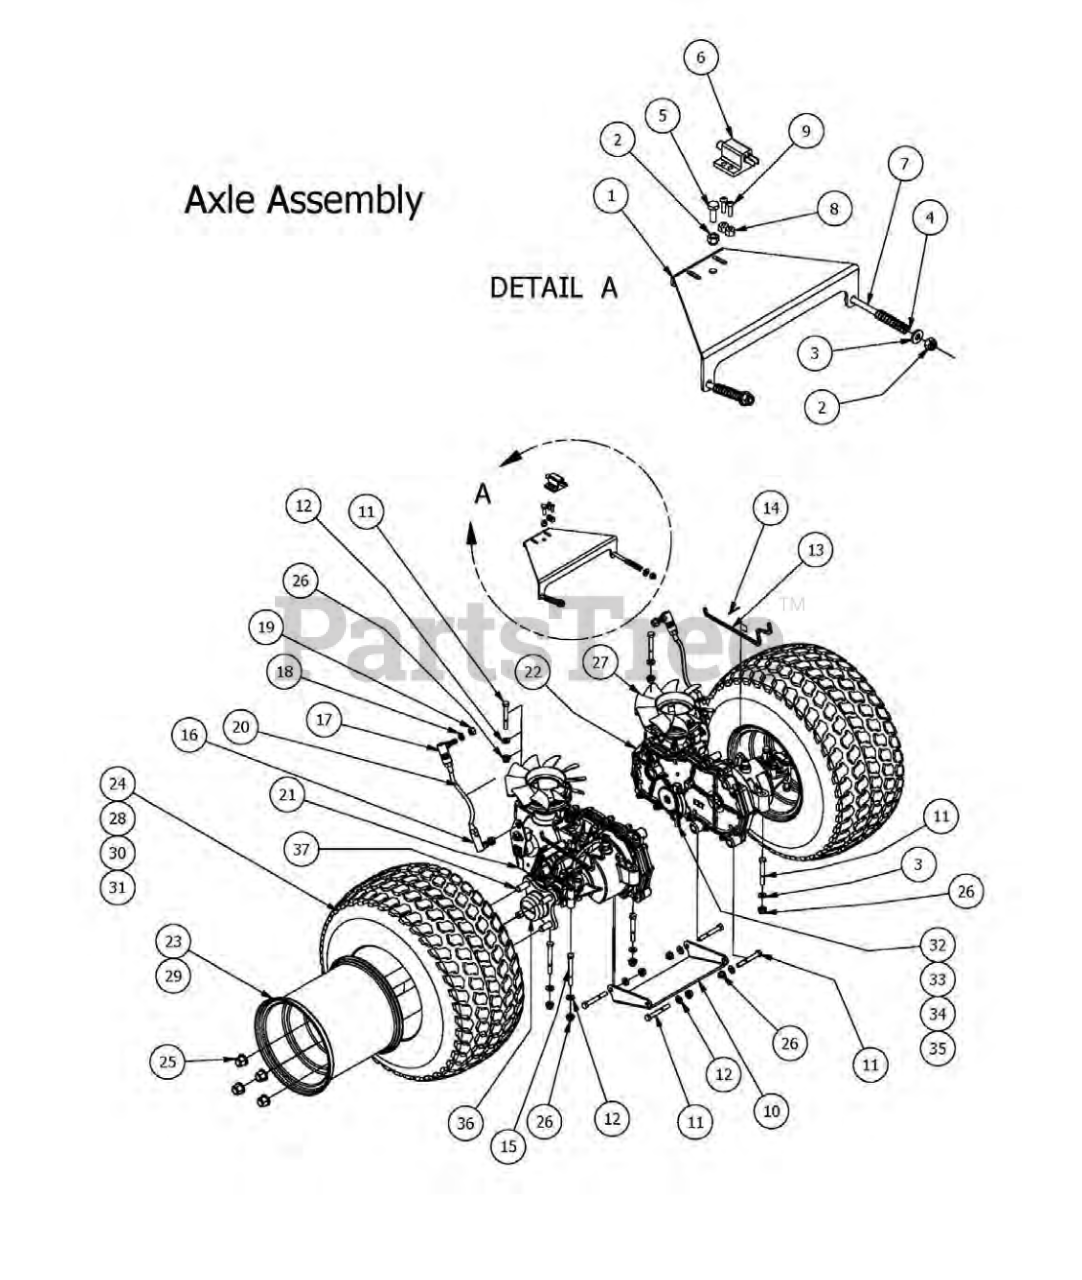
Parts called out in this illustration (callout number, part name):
1	MZ Brake Lock Bracket
2	1/4" Nylock Nut
3	1/4" Flat Washer
4	Brake Spring
5	1/4" x 3/4" Hex Bolt
6	Safety Switch
7	1/4-20 x2-1/2 Gr2 hex C/s zinc
8	10-24 Nylon Insert Locknut
9	10-24 X 5/8 BS Button Head Bolt
10	MZ Transaxle Support (Lower)
11	5/16" x 2 1/2" Bolt
12	5/16" Flat Washer
13	MZ Brake Release Bar
14	Cotter Pin-Brake bar on Mz
15	5/16" x 3" Hex Bolt
16	3/8-24 Ball Joint
17	Quick Release Ball Joint
18	3/8" Lock Washer
19	3/8" Fine Threaded Jam Nut
20	MZ/Magnum Push Rod - 2014
21	EZT- Left MZ Models
22	EZT- Right MZ Models
23	Rear rim for a 48 & 54"
24	18 x 9.50-8 Tire Only MZ 48 &54" Deck only
25	Acorn Lug Nut
26	5/16" Nylon Flange Nut
27	MZ Fan & Pulley Kit
28	42" MZ 18x 7.50-8 tire only
29	Rear rim only 42" MZ
30	18x9.50-8 48 & 54" Deck Tire and Wheel Assembly
31	18x8.50-8/8" 42" Deck Tire and Wheel Assembly
32	MZ Brake Cog Kit
33	MZ Retainer Ring for Brake
34	MZ Brake Gear
35	MZ Brake Arm Kit
36	Mz 4 Bolt Hub Kit
37	Transaxle Wheel Studs
